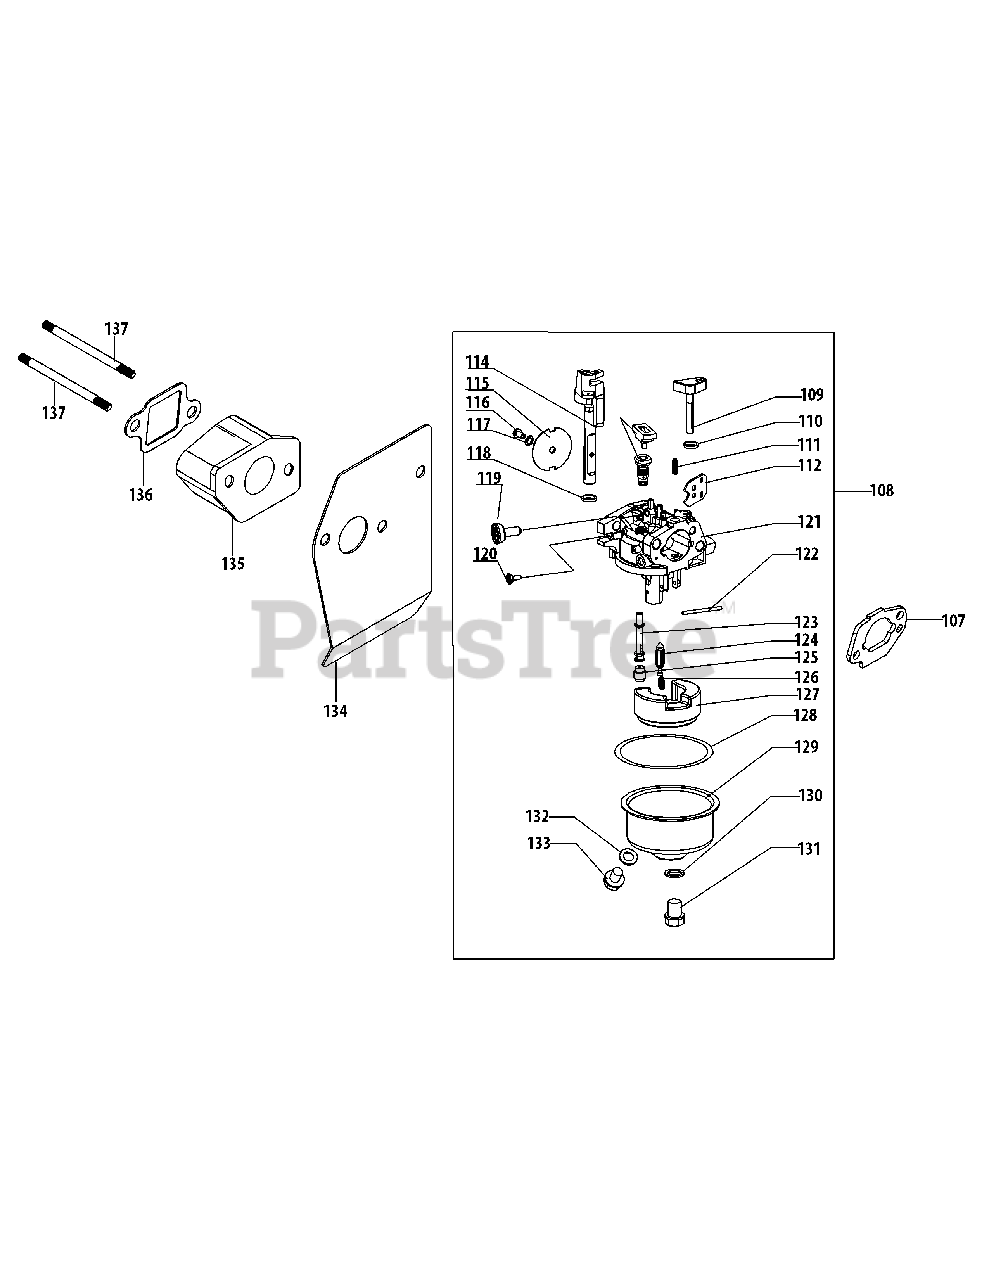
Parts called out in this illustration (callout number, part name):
107	Carburetor Gasket Plate
108	Carburetor Assembly
109	Choke Shaft
110	Fiber O-Ring
111	Choke Plate
112	Choke Detent Spring
113	Idle Jet Assembly
114	Throttle Shaft
115	Throttle Plate
116	Screw M3X6 Throttle Plate
117	Lock Washer
118	Fiber O-Ring
119	Idle Speed Adjusting Screw
120	Idle Mixture Screw
121	Carburetor Body
122	Float Pin
123	Emulsion Tube
124	Needle Valve
125	Main Jet
126	Needle Valve Spring
127	Float
128	Fuel Bowl O-Ring
129	Fuel Bowl
130	Fuel Bowl Gasket
131	Fuel Bowl Mounting Bolt
132	Fuel Drain Plug Gasket
133	Fuel Drain Plug
134	Carburetor Gasket
135	Carburetor Insulator
136	Carburetor Insulator Gasket
137	Carb Stud M6X113
